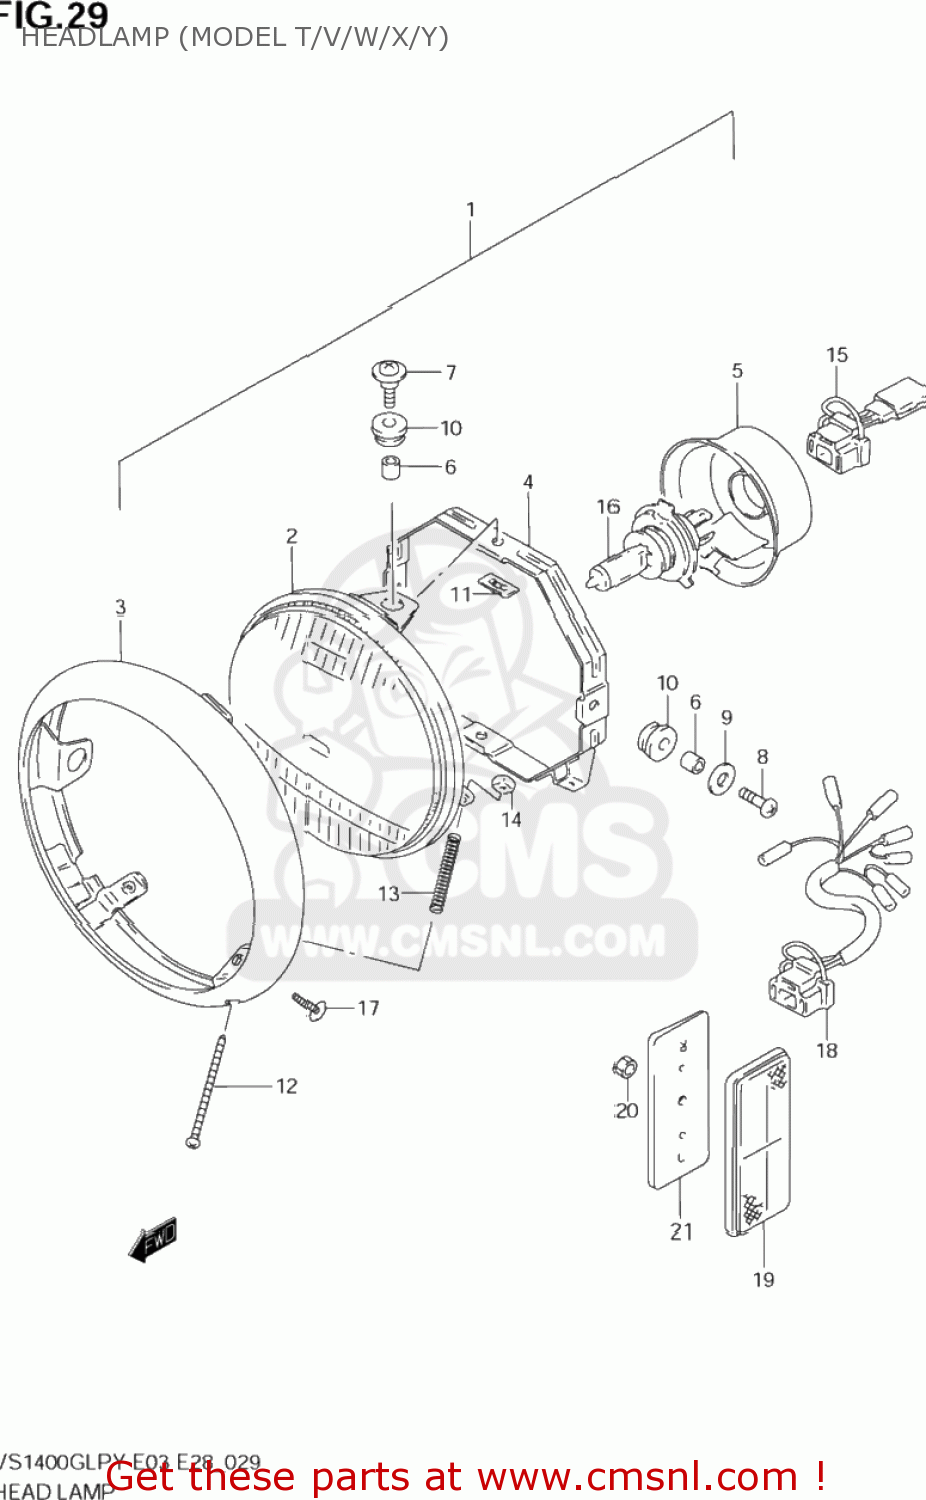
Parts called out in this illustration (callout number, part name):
1	HEADLAMP ASSY
2	UNIT,LAMP
3	RIM
4	RING,MOUNTING
5	COVER,SOCKET
6	SPACER
7	SCREW,MOUNTING
8	SCREW
9	WASHER (5.5X18X1)
10	CUSHION
11	NUT
12	SCREW,ADJUSTING(4X50)
13	SPRING
14	NUT
15	SOCKET
16	BULB(12V60/55W,H4)
17	SCREW
18	WIRE,HEADLAMP LEAD
19	REFLEX REFLECTOR,FR SIDE
20	NUT
21	SPACER,FR SIDE RR
